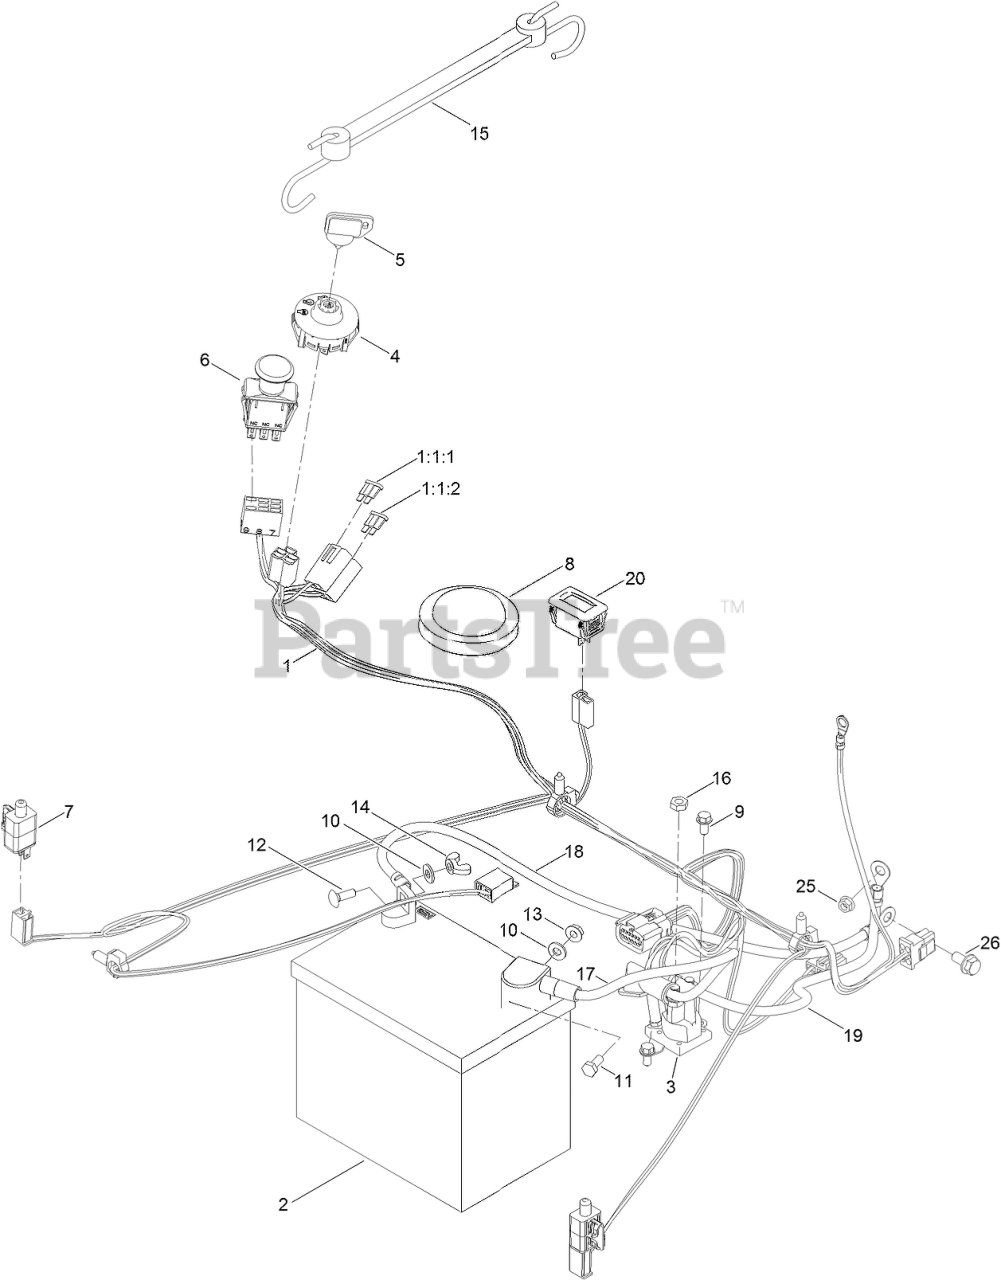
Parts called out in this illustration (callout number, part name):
1	HARNESS-WIRE
1:1:1	FUSE-BLADE, 30 AMP
1:1:2	FUSE-BLADE, 25 AMP
2	BATTERY
3	SOLENOID
4	SWITCH-IGNITION
5	KEY-IGNITION
6	SWITCH-PTO
7	SWITCH
8	SWITCH-SEAT
9	SCREW-HWH
10	WASHER-FLAT
11	SCREW-HH
12	BOLT-CARR
13	NUT-HF
14	NUT-WING
15	HOLDDOWN-BATTERY
16	NUT-JAM
17	CABLE-BATTERY, RED
18	CABLE-BATTERY, POSITIVE
19	CABLE-BATTERY, BLACK
20	HOURMETER
25	NUT-HF
26	SCREW-HHF
